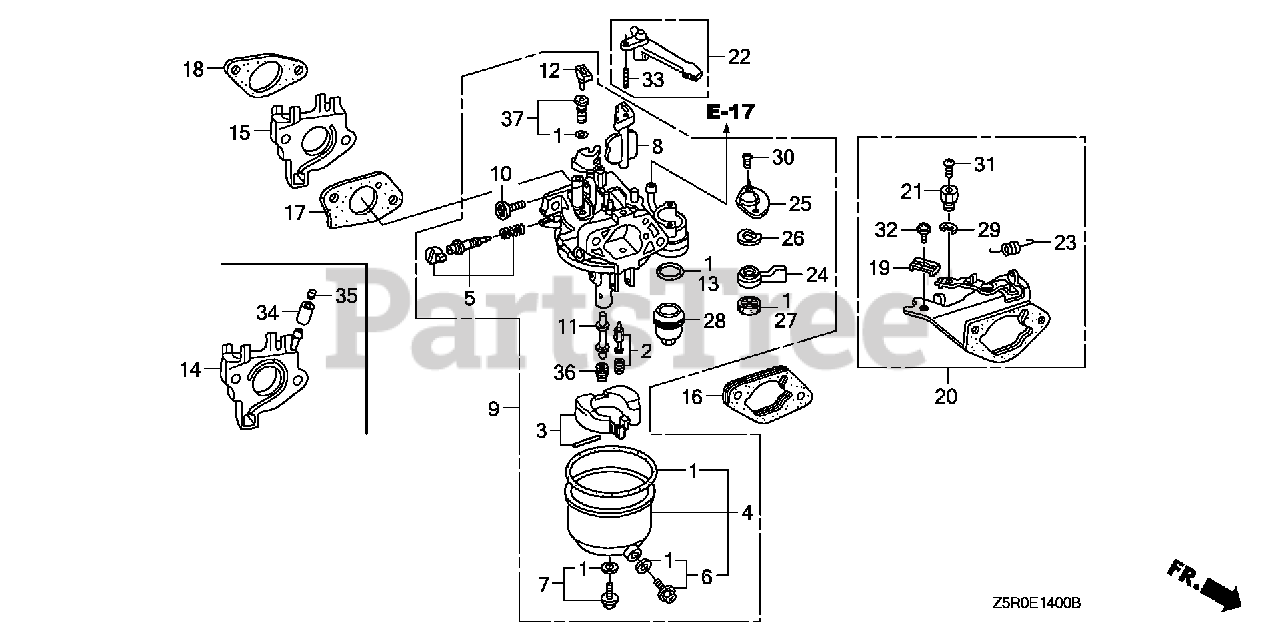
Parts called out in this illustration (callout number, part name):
1	GASKET SET (INCLUDES 16173-001-004)
2	VALVE SET, FLOAT
4	CHAMBER SET, FLOAT
5	SCREW SET, PILOT
6	SCREW SET, DRAIN
7	SCREW SET
9	CARBURETOR ASSY. (BE85B B)
10	SCREW, THROTTLE STOP
11	NOZZLE, MAIN
12	COLLAR, SETTING
13	GASKET, FUEL STRAINER CUP
15	INSULATOR, CARBURETOR
16	SPACER, CARBURETOR
17	GASKET, CARBURETOR
18	GASKET, INSULATOR
22	LEVER, CHOKE (STD)
24	LEVER, PETCOCK
25	PLATE, LEVER SETTING
26	SPRING, PETCOCK LEVER
27	GASKET, PETCOCK
28	CUP, FUEL STRAINER
30	SCREW, PAN (3X6)
33	PIN, SPRING (2X12)
36	JET, MAIN (#88)
36	JET, MAIN (#90)
36	JET, MAIN (#92)
37	JET SET, PILOT (#45)
